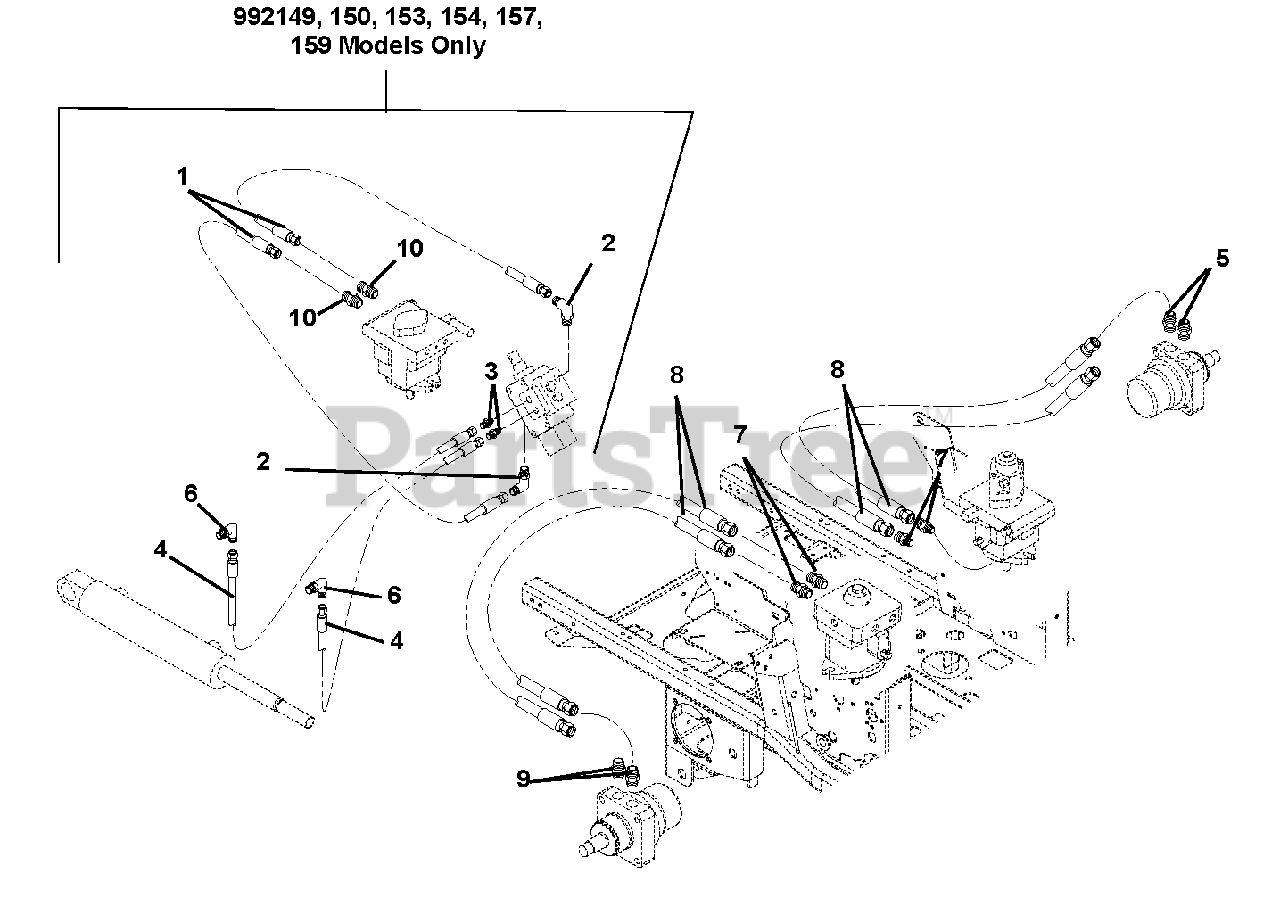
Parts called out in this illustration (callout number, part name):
1	Hose, Hydraulic (992149, 150, 153, 154, 157, 159)
2	Hydraulic, Fitting Elbow (992149, 150, 153, 154, 157, 159)
3	Adapter (4-6F5OLO) (992149, 150, 153, 154, 157, 159)
4	Hose, Hydraulic (992149, 150, 153, 154, 157, 159)
5	Fitting, Hydraulic (8-10 V5OLO) (SN 000101 - 2499)
6	Fitting, Hydraulic (4 C5OLO) (992149, 150, 153, 154, 157, 159)
7	Adapter, Face Seal 8 x 8 .50 O-Ring
8	Hose, Hydraulic .50
9	Adapter, Hydraulic Steel (M10 O-M8F)
10	Fitting, Hydraulic (4 F5OLO) (Supplied with pump) (992149, 150, 153, 154, 157, 159)
